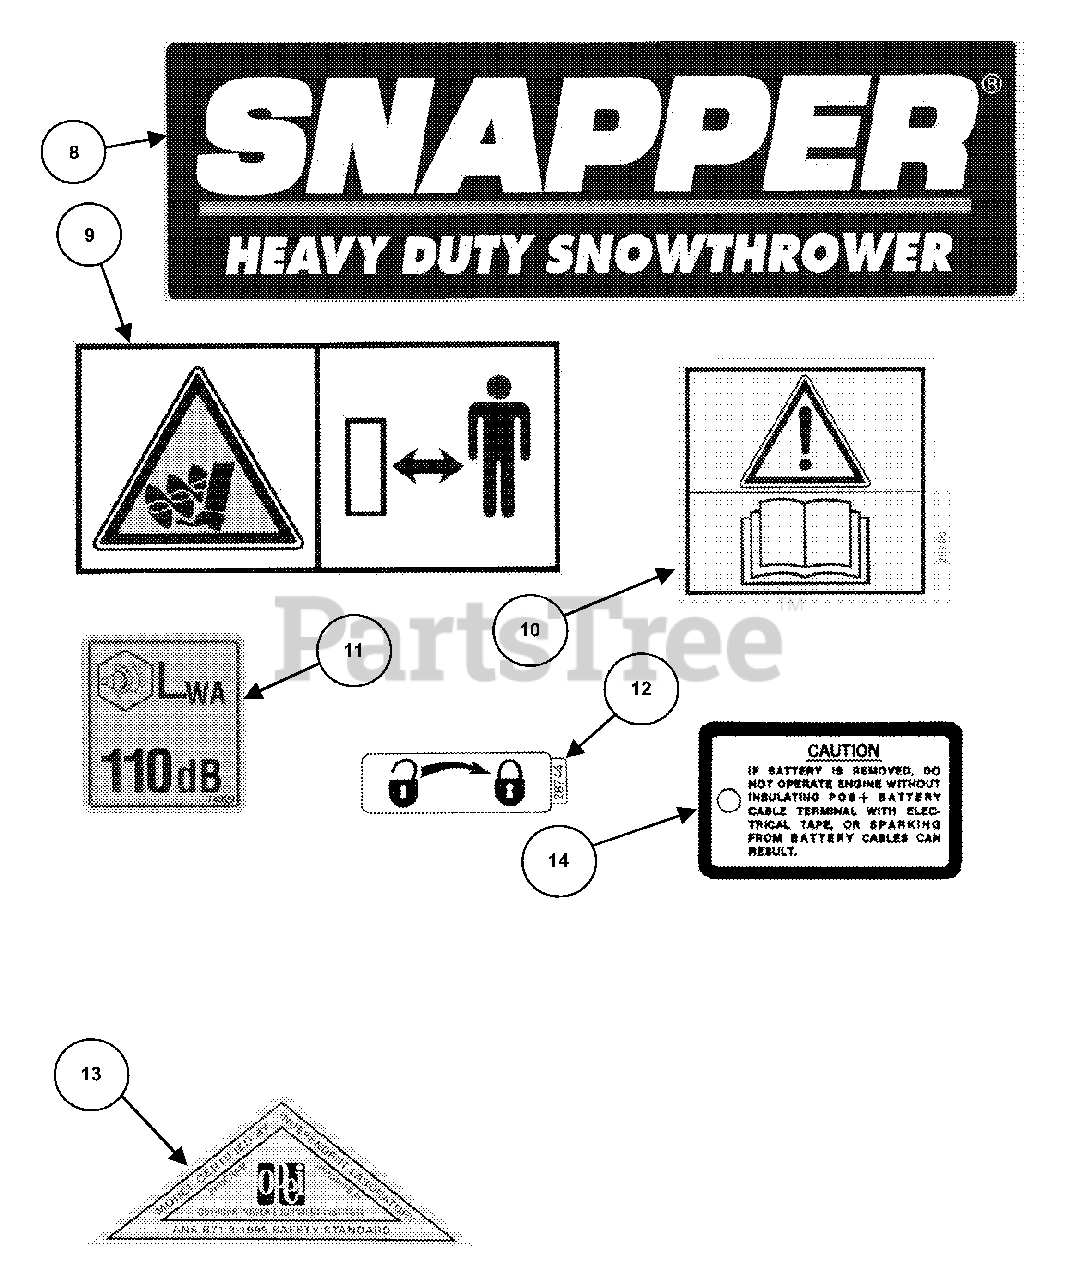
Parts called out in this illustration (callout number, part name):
8	DECAL, Heavy Duty Snow
9	DECAL, Foot Danger (Euro)
10	DECAL, Chute/Read Manual (Euro)
11	DECAL, Sound 110
12	DECAL, Turn To Lock
13	DECAL, OPEI Snow
14	DECAL, Caution Tag
